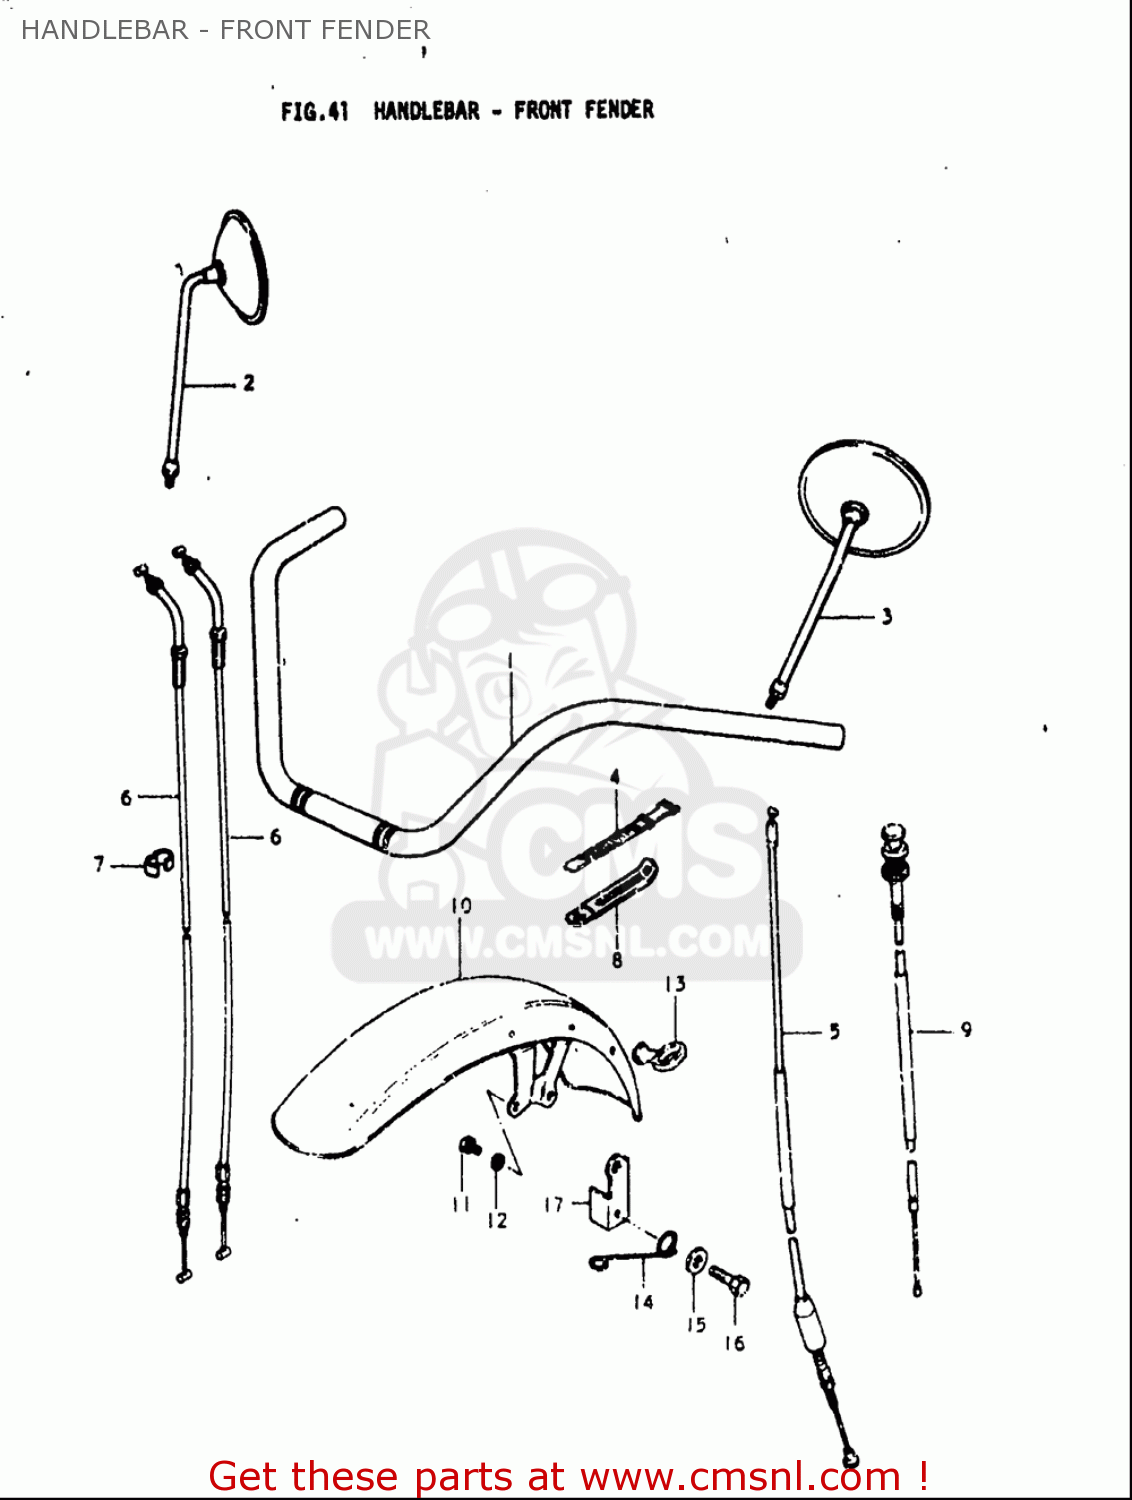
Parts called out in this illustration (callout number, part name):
1	HANDLEBAR
2	MIRROR ASSY,RR VIEW,R
3	MIRROR ASSY,RR VIEW,L
4	CLAMP(L:120)
5	CABLE ASSY,CLUTCH
6	CABLE ASSEMBLY,THROTTLE
7	CLIP
8	CLAMP(L:65)
9	CABLE ASSY,STARTER
10	FENDER,FR
11	BOLT
12	WASHER,LOCK
13	GUIDE,CABLE
14	GUIDE,SPEEDOMETER CABLE
15	WASHER
16	BOLT
